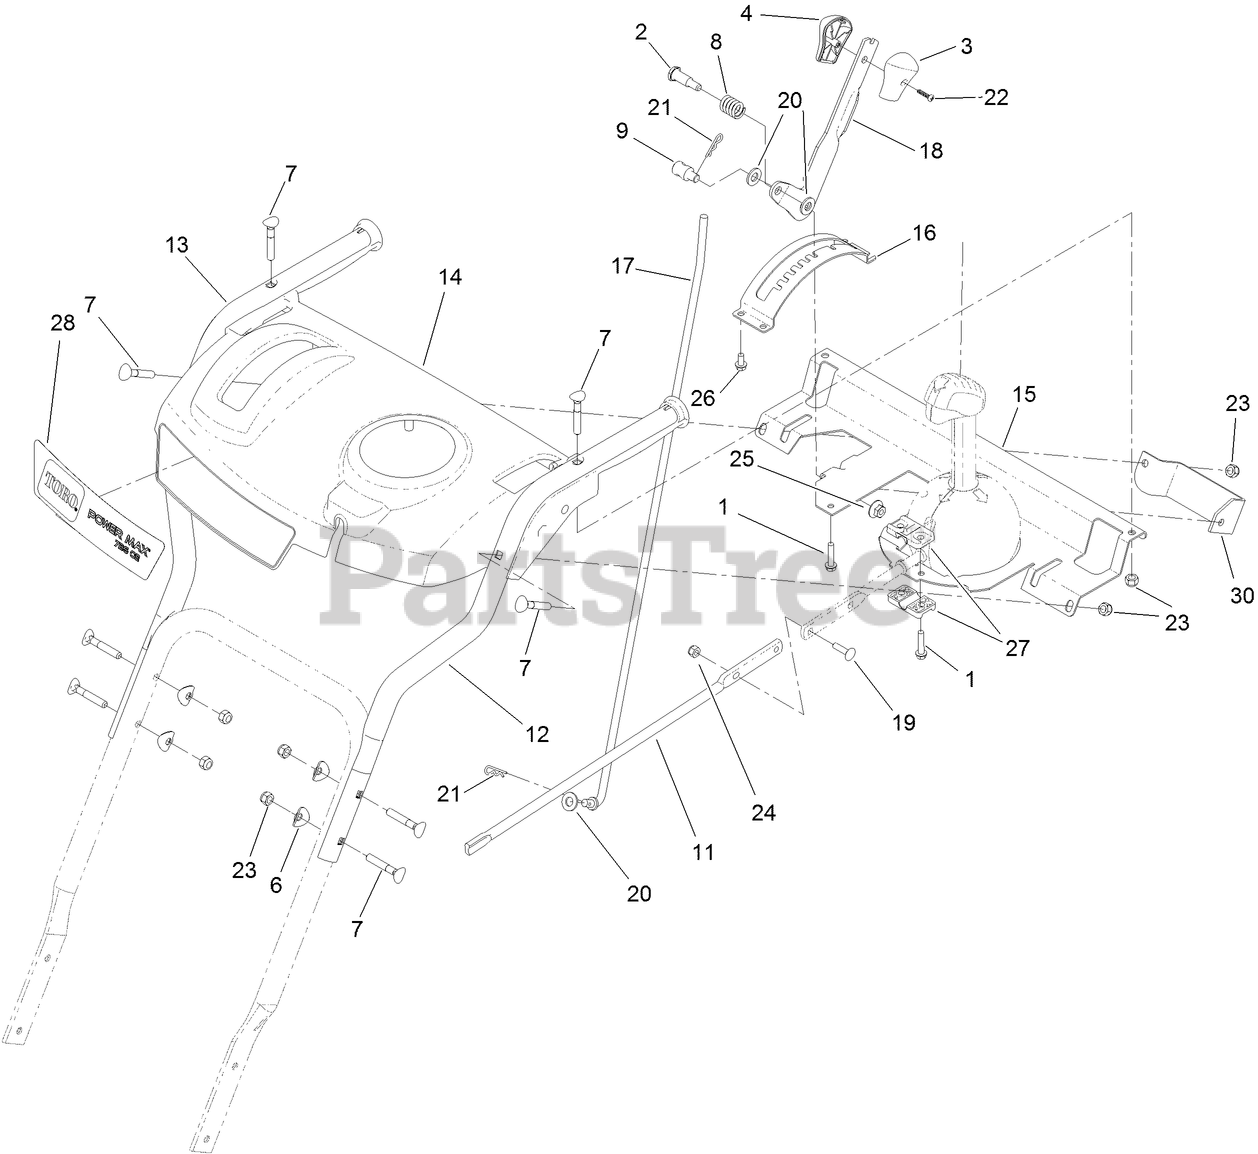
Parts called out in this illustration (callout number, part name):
1	SCREW-PLASTITE
2	SCREW-SHOULDER
3	KNOB-SHIFT, LH
4	KNOB-SHIFT, RH
6	WASHER
7	SCREW-HANDLE
8	SPRING-COMPRESSION
9	TRUNNION-ROD
11	ROD-CHUTE, FRONT
12	HANDLE-UPPER, LH
13	HANDLE-UPPER, RH
14	PANEL-CONTROL, MASTER
15	SUPPORT-PANEL, CONTROL
16	MOUNT-SELECTOR, SPEED
17	ROD-SELECTOR, GEAR
18	SELECTOR-SPEED
19	SCREW-CARR
20	WASHER-FLAT
22	SCREW-PPH
23	NUT-LOCK, NI
24	NUT-LOCK, NI
25	NUT-HF
26	SCREW-PLASTITE
27	SUPPORT-ROD
30	PLATE-SUPPORT, SHIFT
